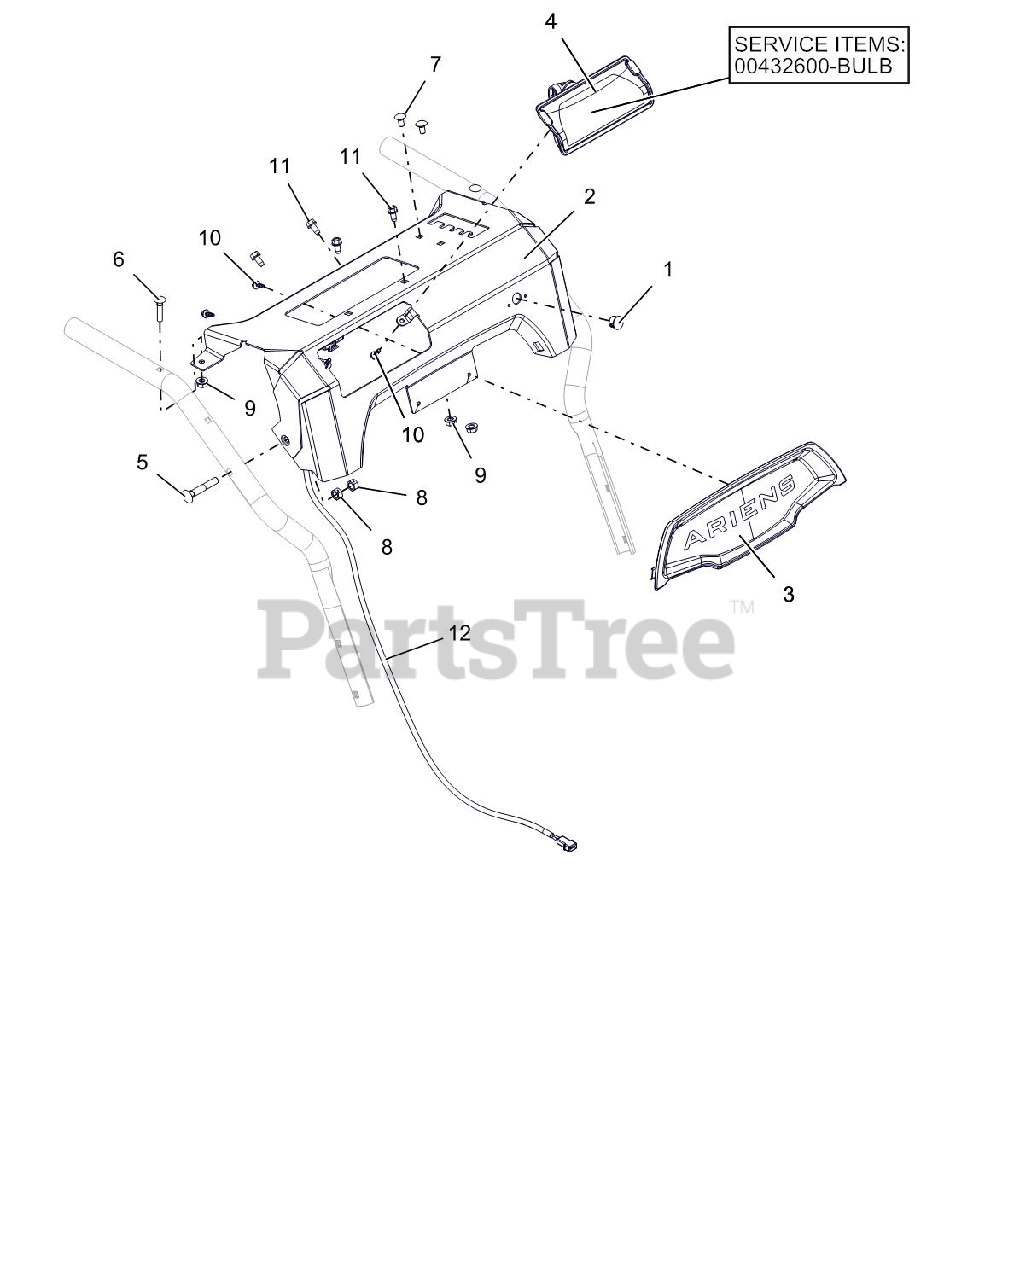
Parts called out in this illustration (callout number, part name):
1	HOLE PLUG, PLASTIC .56 HOLE
2	CRTL PANEL W/DECAL-COMP MANUAL
3	BEZEL, DASH - ARIENS SM DASH
4	BULB, LIGHT-HALOGEN 20W
4	HEADLIGHT ASY, HALO 20W 2SHOT
5	BLT-RDHDXLSQNK .31-18X2.0 G5YZ
6	BLT-RDHDXLSQNK.25-20X1.25 G5ZC
7	@BLT-RDHDSQNK .25-20X.50 G5YZ
8	@NUT-LK-CTR .31-18 YWZC
9	@NUT-LK-TOP-FLG .25-20 YWZC
10	SCR-TAP #10X.50 BOSS INDHXHD
11	SCR-TAP .25-20X.50 HWH TR YWZ
12	HARNESS, LIGHT - COMPACT
